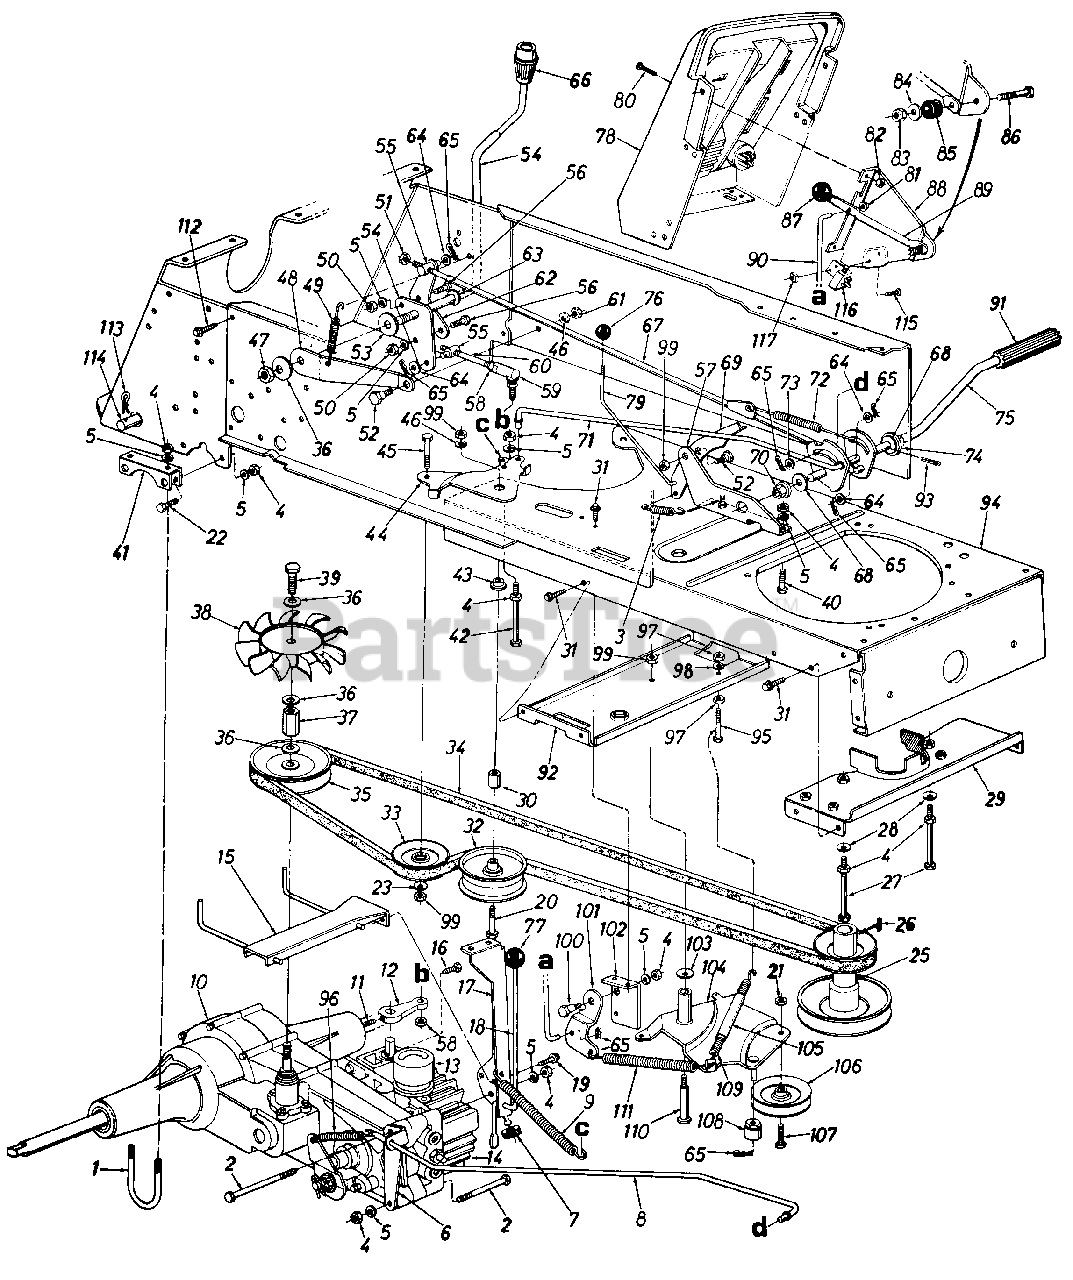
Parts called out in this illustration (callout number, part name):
1	U-Bolt 5/16-18 x 3.25" Lg.
2	Hex Patch Bolt 5/16-18 x 4.5" Lg. (Gr. 5)
3	Ext. Spring .5" O.D. x 1.55"
4	Hex Nut 5/16-18 Thd.*
5	L-Wash. 5/16" I.D.
6	Brake Rod Guide Brkt.
7	Rubber Wash. .33" I.D. x .87"
9	Ext. Spring .62" O.D. x 6.12" Lg.
11	Set Screw 5/16-24 x .38" Lg.
12	Pintle Shift Lever
13	Reservoir
14	Hydrostatic Pump
15	Belt Guard Ass'y.
16	Hex Bolt 5/16-18 x 4.5" Lg. (Gr. 5)
17	Transaxle Torque Bracket
18	Transaxle Control Rod
19	Hex Wash. Hd. B-Tap Scr. 5/1 6-1 8
20	Hex Bolt 3/8-16 x 2.75" Lg.
21	Hex Cent. Lock Nut 3/8-16 Thd.
22	Hex Bolt 5/16-18 x .75" Lg. (Gr. 5)
23	Fl-Wash. .385" I.D. x .87" O.D.
25	Engine Pulley
26	Sq. Key 1/4 x 1.5" Lg.
27	Hex Bolt 5/16-18 x 5.25" Lg.
28	Bell-Wash. .345" I.D. x .88" O.D.
29	Belt Keeper Brkt. Ass'y.
30	Spacer .375" I.D. x .75" Lg.
31	Hex Wash. Hd. TT-Tap Scr. 1/4-20 x .5" Lg.
32	Fl-ldler Pulley 3.25" Dia.
33	V-Belt Idler
34	V-Belt
35	Transmission Pulley 4.25" O.D.
36	Bell-Wash. .56" I.D. x 1.5"
37	Fan Adapter Nut 9/16-18 Thd.
39	Hex Bolt 9/16-18 x .5" Lg.
40	Hex Bolt 5/16-18 x .75" Lg.
41	Transaxle Mtg. Bracket
42	Hex Bolt 5/16-18 x 2.75" Lg.
43	Shld. Spacer .625" I.D.
44	Clutch Idler Bracket
45	Hex Bolt 3/8-16 x 1.5" Lg.
46	L-Wash. 3/8" I.D.
47	Hex Jam Nut 1/2-20 Thd.
48	Speed Control Rod Torque Brkt.
49	Ext. Spring 2.5" Lg.
50	Hex Nut 5/16-24 Thd.
51	Hex Jam Nut 3/8-24 Thd.
52	Shld. Bolt .50" Dia. x .170"
53	Fiber Washer .54" I.D. x 1.75"
54	Speed Control Handle Ass'y.
55	Ferrule 3/8-24 Thd.
56	Hex Bolt 5/16-24 x .62" Lg.
57	Foot Pedal Mtg. Brkt.
58	Hex Jam Nut 3/8-24 L.H. Thd.
59	Ball Joint Ass'y.
60	Control Rod 3/8-24 x 3.75" Lg.
61	Hex Nut 3/8-16 Thd.
62	Speed Selector Handle Brkt.
63	Fl-Wash. .531" I.D. x 1.25" O.D.
64	Fl-Wash. .385" I.D. x .62" O.D.
65	Internal Cotter Pin
67	Neutral Return Rod
68	Fl-Wash. .64" I.D. x 1.24" O.D.
69	Parking Brake Lock Brkt.
70	Hex Flange Brg. .634" Dia.
71	Clutch Idler Rod
72	Extension Spring 8" Lg.
73	Fl-Wash. .344" I.D. x .62" O.D.
74	Flange Bearing w/Flats
75	Foot Pedal Ass'y.
76	Ball Knob Brake
77	Ball Knob 1/4-20 Thd.
78	Dash Panel Ass'y.
79	Parking Brake Link
80	Truss Mach. Scr. 1/4-20 x .5" Lg.
81	Push Nut 1/4" O.D. Rod
82	Hex Sems Nut 1/4-20 Thd.
83	Hex Patch L-Nut 1/4-20 Thd.
84	Fl-Wash. .281" I.D. x .73" O.D.
85	Rubber Wash. .33" I.D. x .87"
86	Hex Bolt 1/4-20 x 1.25" Lg.
87	Knob-Blade Clutch
88	Deck Clutch Cont. Brkt.
89	Blade Clutch Lever
90	Deck Control Rod
91	Foot Pad
92	Deck Idler Support Brkt.
93	Cotter Pin 1/8" Dia.
94	Lower Frame
95	Hex Bolt 1/4-20 x 2" Lg.
96	Ext. Spring 3.675" Lg.
97	Hex Nut 1/4-20 Thd.
98	L-Wash. 1/4" I.D.
99	Hex Cent. L-Nut 3/8-16 Thd.
100	Shld. Bolt .437" Dia. x .162"
101	Deck Control Pivot Brkt.
102	Parking Brake Mtg. Brkt.
103	Bell-Wash. .380" I.D. x .88" O.D.
104	Idler Brkt. Deck Ass'y.
105	Convoluted Conduit 4" Lg.
106	V-Belt Idler
107	Hex Bolt 3/8-24 x 1.5" Lg.
108	Spacer
109	Ext. Spring 6.37" Lg.
110	Shld. Bolt .498" Dia. x 2.05"
111	Ext. Spring 6.12" Lg.
112	Hex Wash. AB-Tap Scr. 5/16 x .75" Lg.
113	Hitch Pin Clip
115	Truss Mach. Scr. #10-24 x .5"
116	Safety Switch
117	Hex Nut #10-24 Thd.
